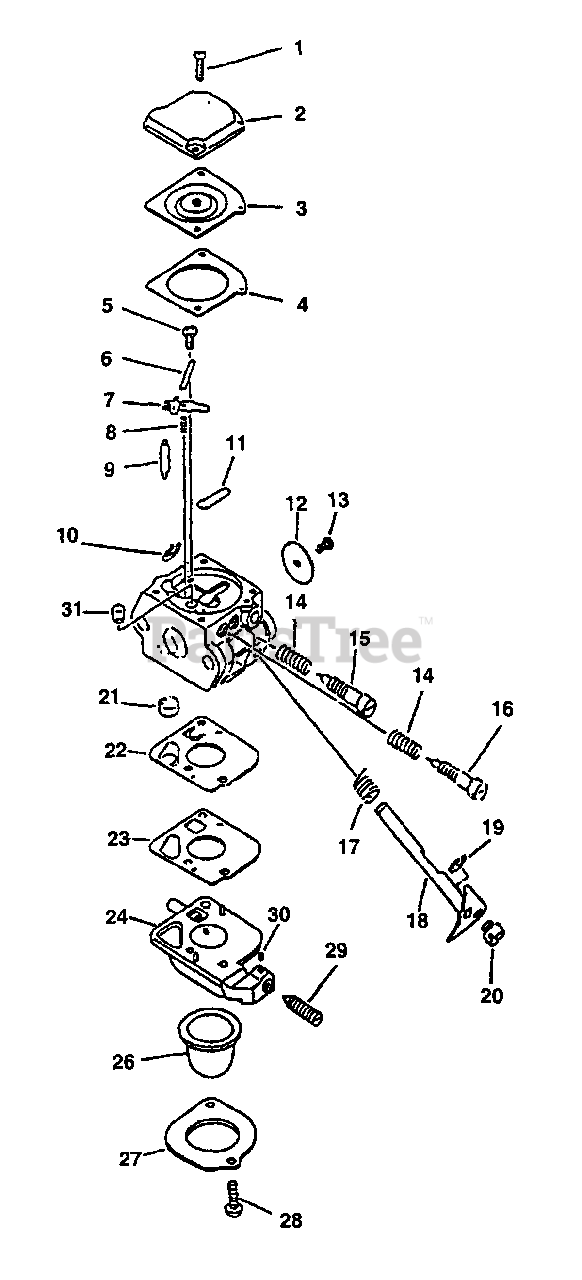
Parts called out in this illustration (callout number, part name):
2	COVER, METERING
3	DIAPHRAGM
4	GASKET, METERING
5	SCREW, METERING LEVER PIN
6	PIN
7	LEVER, METERING
8	SPRING, METERING LEVER
9	VALVE, NEEDLE
10	RING, RETAINING
11	PLUG, WELCH
12	VALVE, THROTTLE
15	NEEDLE - MIXTURE
16	NEEDLE - HIGH SPEED
17	SPRING, RETURN
18	SHAFT, THROTTLE
19	RING, RETAINING
21	STRAINER
22	DIAPHRAGM, PURGE
23	GASKET, PURGE
24	BASE, PURGE
26	BULB, PURGE
27	RETAINER, PURGE BULB
28	SCREW, RETAINER
29	SCREW, IDLE ADJUST
30	PIECE, FRICTION
31	NOZZLE, CHECK VALVE
